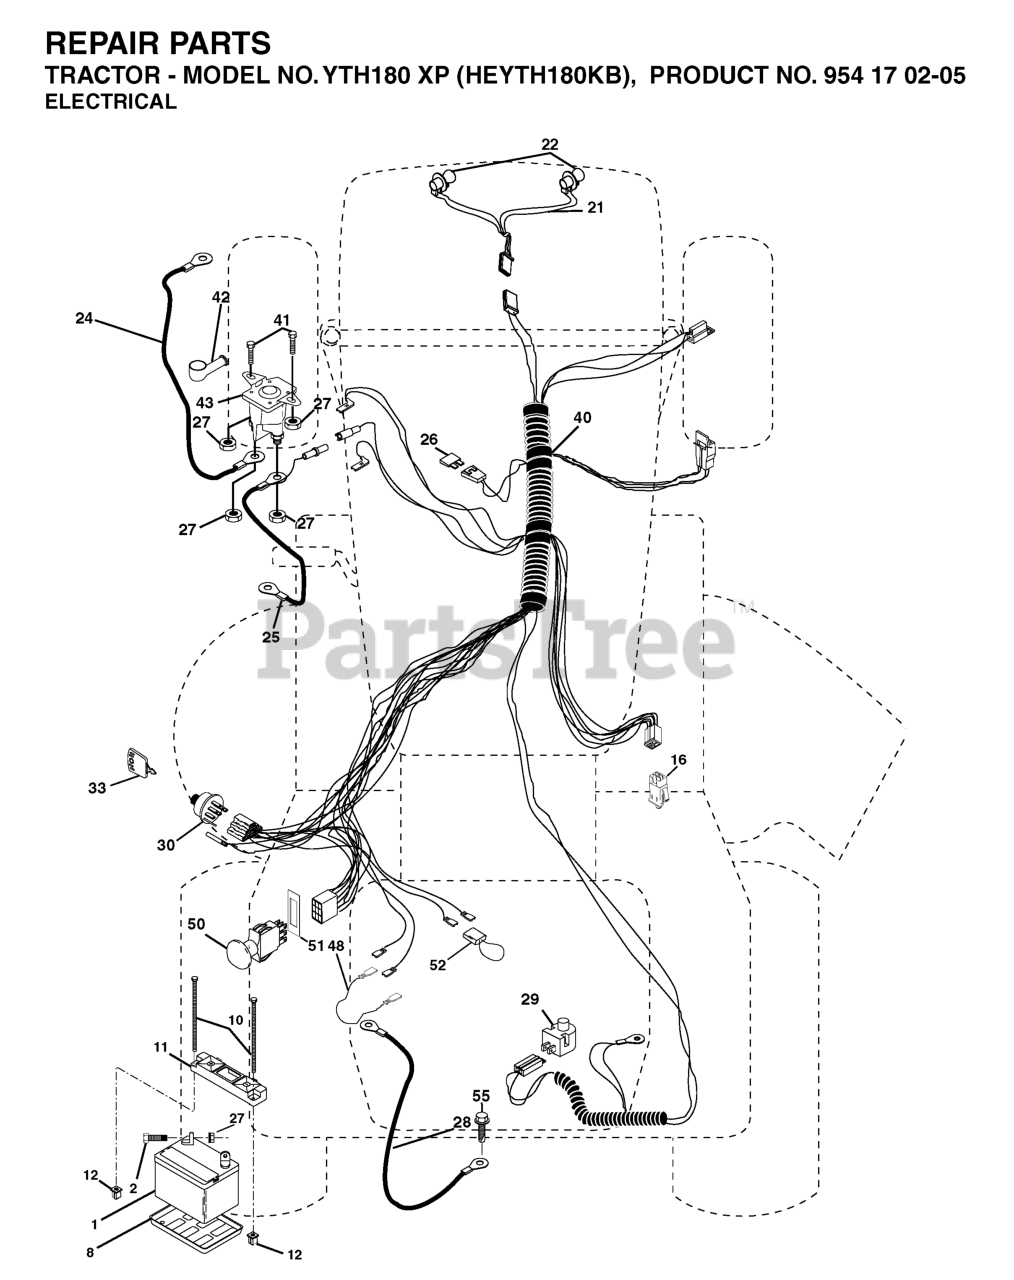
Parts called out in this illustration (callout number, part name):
1	BATTERY 12V .35 AMP
2	BOLT.HEX.1/4.X.3/4.DICHROMATE
8	BATTERY TRAY T
10	BOLT 1/4-20 X 7.5
11	BATTERY HOLDDOWN FRONT MOUNT
12	NUT, PUSH NYLON 1/4" BATTERY
16	SWITCH INTERLOOK PUSH-IN
21	HARNESS.W/LIGHT SOCKET
24	BATTERY CABLE GT
25	CABLE BATTERY 6 GA 22" W/16W
26	FUSE 20AMP
27	NUT
28	CABLE GROUND 6 GA 21" 90T BLK
29	RP.SWITCH.PLUNGER.NC.GRAY
30	IGNITION SWITCH
33	KEY MLD GEN DELTA
40	HARNESS.IGNITION
41	BOLT
42	TERMINAL COVER
43	SOLENOID
48	ADAPTER.AMMETER
50	RP.PTO.SWITCH.8 TERMINAL.BLACK
51	FRAME RETAINING RING
52	WIRE PROTECTION LOOP
55	Screw 5/16-18 x 1/2 Hex, Self Tapping 5/16-18 x 1/2
